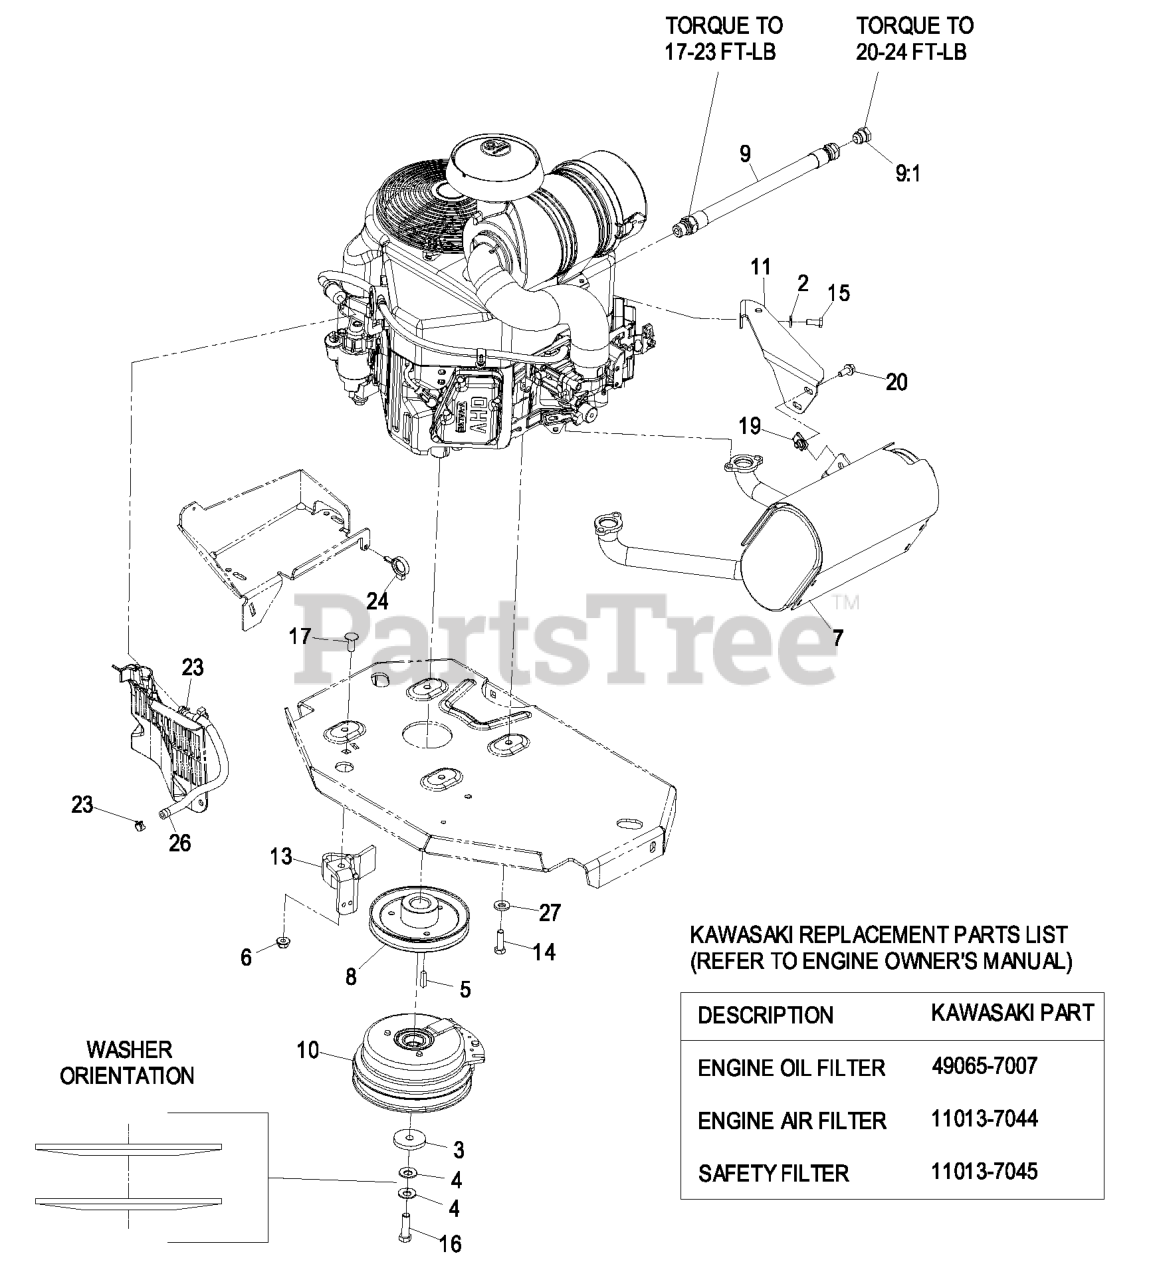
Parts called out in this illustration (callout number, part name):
2	WASHER-SPRING
3	WASHER-CLUTCH
4	WASHER-SPRING
6	NUT-HF, NI
7	MUFFLER
8	SHEAVE
10	CLUTCH KIT
11	BRACKET-MUFFLER
13	CLUTCH-ANCHOR
14	SCREW-HH
15	SCREW-HH
16	SCREW-HH 7/16-20 X 1 1/2 W/LOCTITE
17	SCREW-CARR
20	SCREW-HHF
23	CLAMP-HOSE
24	CLAMP-HOSE
26	HOSE-FUEL
27	WASHER-BELLEVILLE
